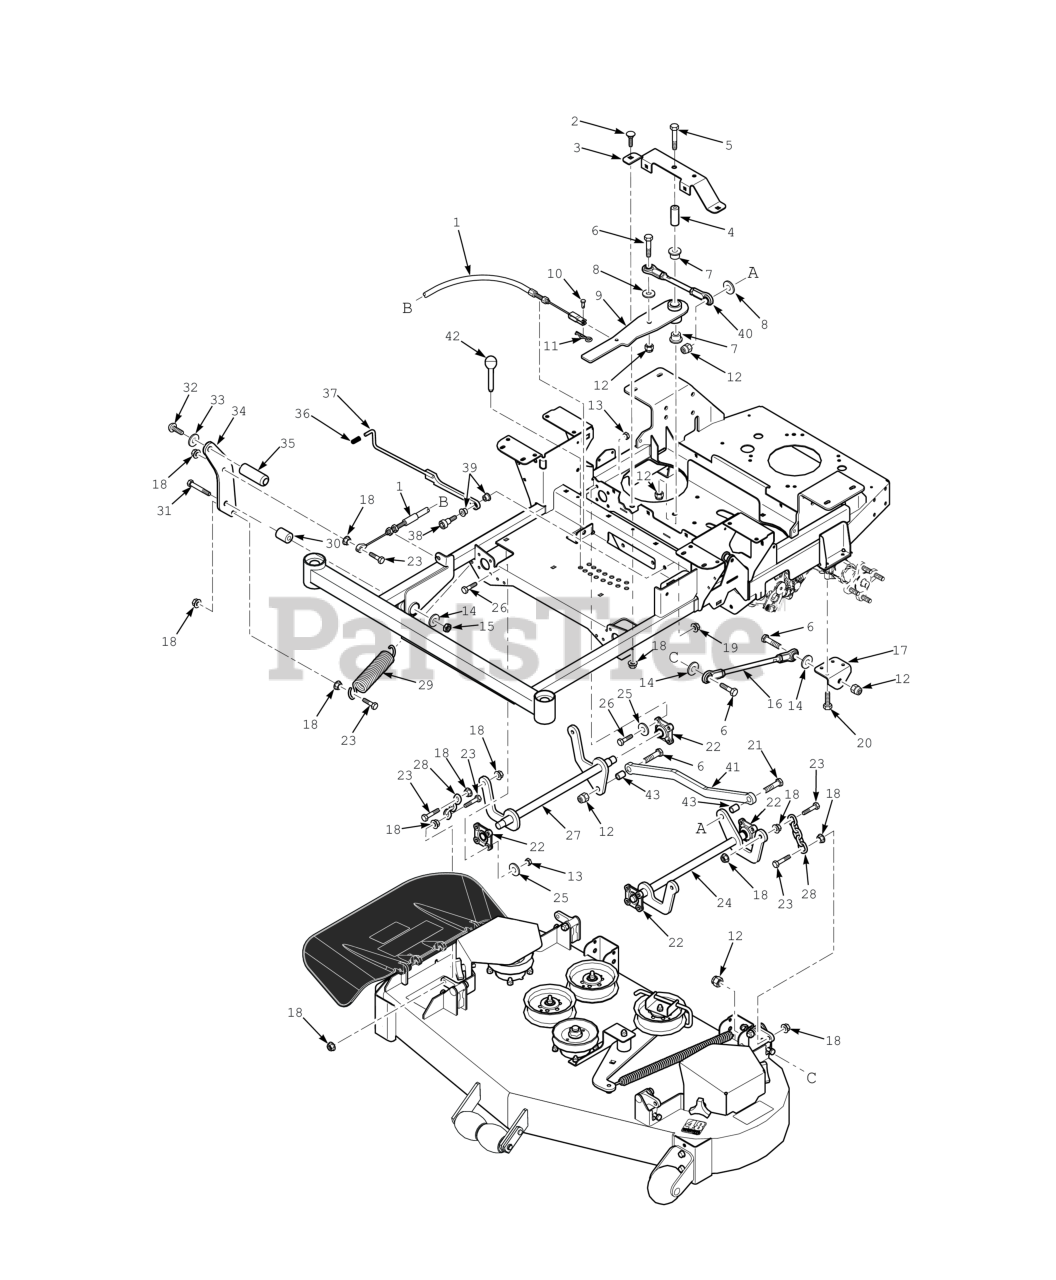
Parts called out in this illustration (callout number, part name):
1	Cable, Deck Lift
2	Bolt, Carriage 3/8-16 x 3/4"
3	Support, Idler Arm
4	Spacer, Deck Lift Pivot
5	Bolt, Hex Head, 1/2-13 x 3-1/4"
6	Hex Head Bolt, 1/2-13 x 2"
7	Bearing, Plastic
8	Flatwasher, 1/2 - .531 x 1.062 x .095
9	DECKLIFT BELLCRANK ASSY, SFZ
10	Clevis Pin, 5/16 x 3/4"
11	COTTER PIN, HAIR - 0.94 X 1.62
12	HEX LOCKNUT, ELASTIC STOP, 1/2-13
13	HEX NUT, ELASTIC STOP LOCK, 5/16-18
14	Flat Washer, 1/2 (.562 x 1.375 x .109)
15	HEX NUT, ELASTIC STOP LOCK, 3/8-16
16	Linkage, Push Arm
17	Bracket, Push Arm Link
18	NUT, 3/8-16 SERRATED FLANGE HEX HEAD
19	HEX NUT, ELASTIC STOP LOCK, 3/8-16
20	Bolt, Hex Head 5/16-18 x 3.00"
21	Bolt, Hex Head 1/2-13 x 3"
22	Bearing, Deck Lift - 48V & 52V
23	Bolt, Hex Head 3/8-16 x 1-1/2" B&S 32BV
24	Weldment, Deck Lift LH
25	Flatwasher, 1/4" (.312 x .750 x .065")
26	Bolt, Heax Head 5/16-18 x 1" (48V / 52V)
27	Weldment, Deck Lift RH
28	Chain, Deck Lift
29	Spring, Deck Lift
30	Spacer, Deck Lift Pivot
31	Bolt, Hex Head 1/2-13 x 3"
32	Bolt, Head Socket 5/8-11 x 1-1/2"
33	Lockwasher, 5/8" Spring
34	Pedal, Foot Bracket
35	Foot Pedal, Height Adjustment
36	Grip, Deck Latch
37	Weldment, Deck Latch
38	Bolt, Shoulder 1/2 x 1/2"
39	Bearing
40	Linkage Assembly, Deck Lift
41	Mounting Bracket, Fuel Tank Front
42	Pin, Height Adjuster
43	Sleeve
